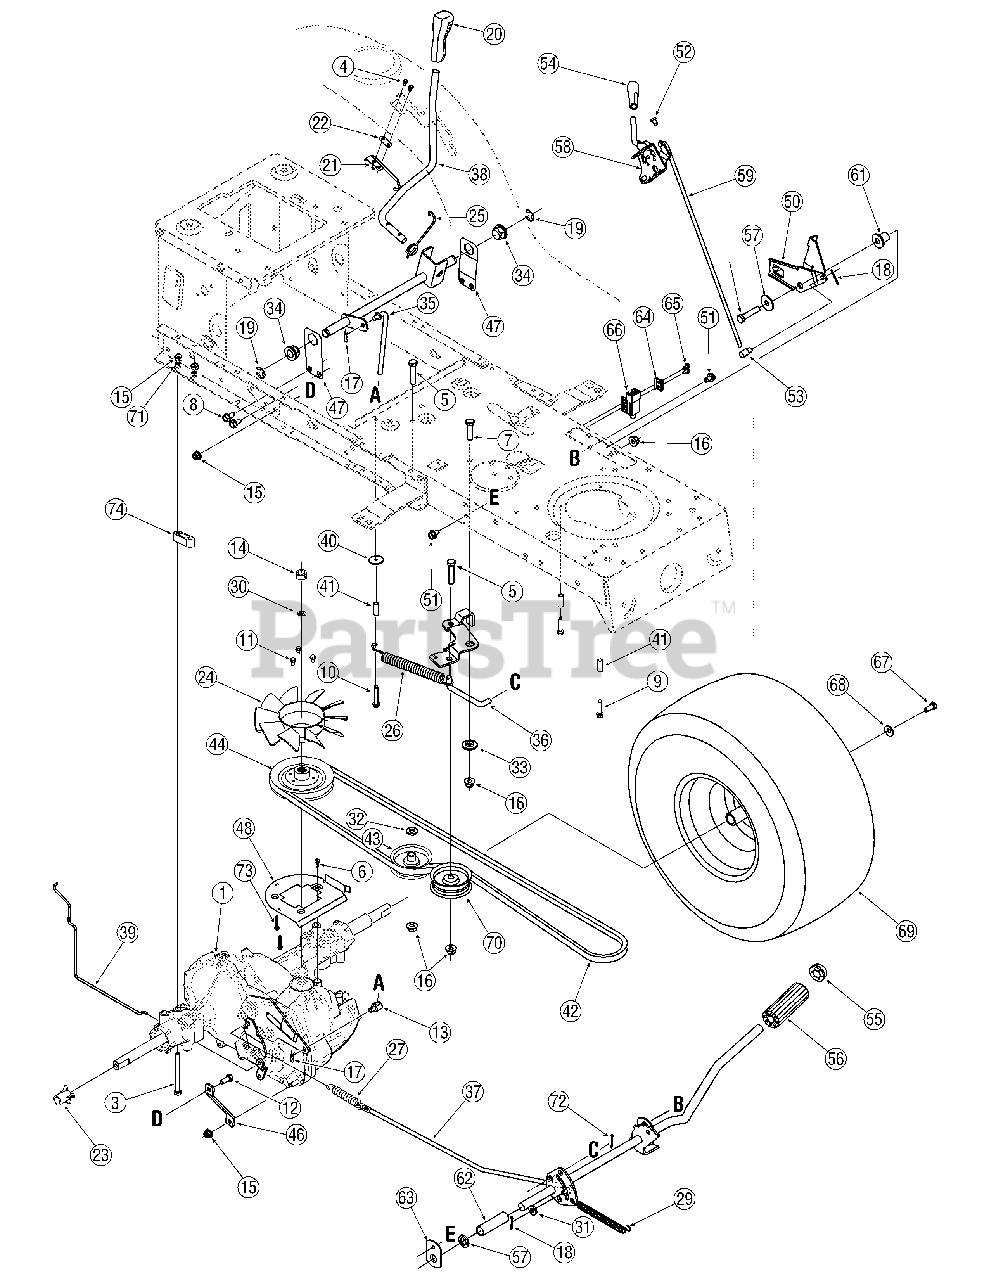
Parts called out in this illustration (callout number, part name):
1	Transmission Assembly, Hydro
2	Control Assembly, Hydrostatic
3	Hex Screw, 5/16-18, 2.75, Gr5,
3	Hex Screw, 5/16-18, 3.50, Gr5,
4	Screw, #8-18, 0.500
5	Hex Screw, 3/8-16, 1.75
6	Screw, B, #10-16, 0.500
7	Hex Screw, 3/8-16, 1.00, Gr5
8	Screw, 5/16-18, 0.625
9	Screw, 1/4-20, 1.250
10	Screw, 1/4-20, 1.625
10	Screw, 1/4-20, 1.75
11	Screw, #12-24, 0.375
12	Hex Screw, 5/16-18, .75, Gr5
13	Ferrule, 5/16-24 x .312 Dia.
14	Nut, Hex Lock, 1/2-20, Gr5
15	Nut, Flange Lock, 5/16-18, Grf
16	Nut, Flange Lock, 3/8-16, Grf
17	Pin, Cotter, .072 Dia. x 1.13
18	Pin, Cotter, 3/32, 1.0
19	Ring, E-Type, .625 Dia.
20	Grip, Handle, 1/2
21	Spring Switch, Hydro
22	Plate, Insulator Nut
23	Sleeve, .765 x 1.50
24	Fan, 10"
25	Spring, Torsion
26	Spring, Extension, .75 OD x 6.02
27	Spring, Extension, .59 OD x 4.00
29	Spring, Extension, .50 Dia x 6.37
30	Washer, Lock, 1/2
31	Washer, Flat, .344 x .750 x .120
32	Washer, Flat, .407x.812x.135
33	Spacer, Shoulder, .625 ID x .169
34	Bearing, Hex Flange
35	Control Rod, Hydrostatic
36	Declutching Rod
37	Brake Rod, Hydrostatic
37	Brake Rod, Hydrostatic 46" Deck
38	Control Handle, Hydrostatic
39	Bypass Rod, Hydrostatic
39	Bypass Rod, Hydrostatic 46" Dk.
40	Shoulder Spacer, .375 x .274
40	Washer, Flat, .285 x 1.25 x .06
41	Spacer, .260 x .372 x 1.030
41	Spacer, .260 x .372 x 1.420
42	Belt, V-Type
43	Idler Pulley, Flat 2.75 OD
44	Pulley, Input, 5.0 OD
51	Screw, 5/16-18, 0.50,
52	Screw, 1/4-14, 0.625
53	Ferrule 1/4-20
55	Push Cap, 5/8
56	Foot Pad, 4.0
57	Washer, Flat, .406 x 1.25 x .157
58	Lever, Parking Brake
60	Hex Screw, 3/8-16, 2.00
61	Spacer, Flange, .390 x .671 x .95
62	Spacer, .640 x .76 x 2.63
63	Support Bracket, Pedal
64	Plate, Switch
65	Pop Rivet, .187 dia.
66	Switch, Interlock
67	Screw, 5/16-24, .750, Gr5
68	Bell Washer, .34 x .872 x .060
70	Idler Pulley, Flat 2.75 OD
71	Washer, Lock 5/16 Ext. Tooth
72	Pin, Cotter, 3/32 x 1.25
73	Screw, #10-24 x 0.75
74	Spacer, .68
